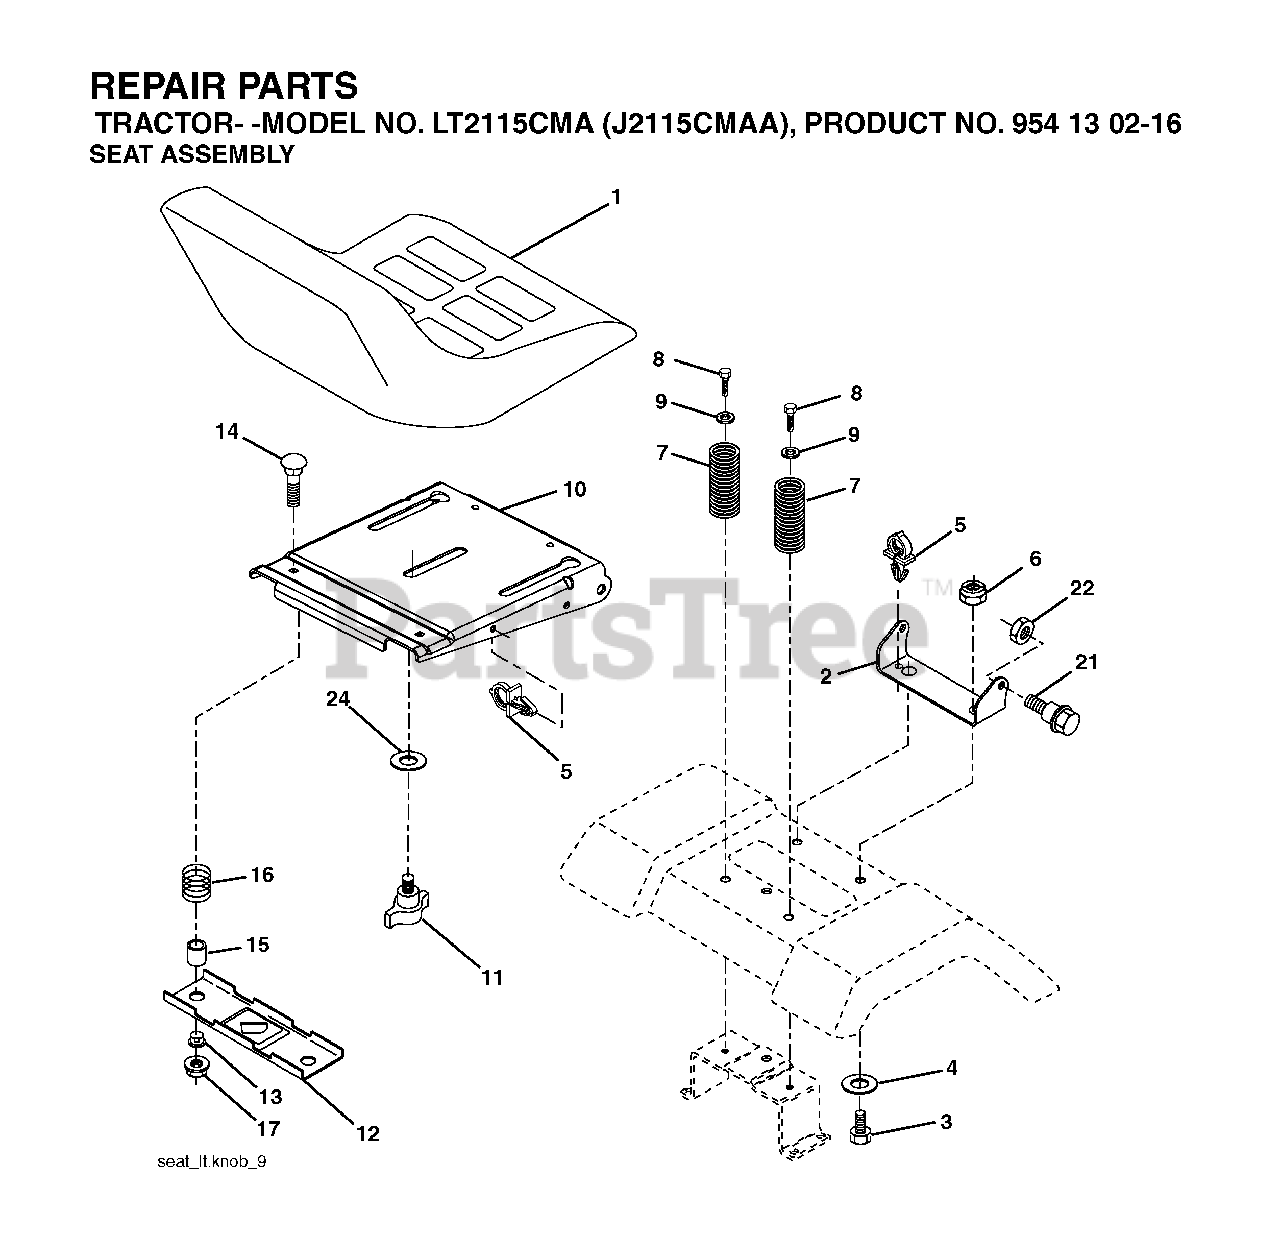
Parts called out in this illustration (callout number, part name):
2	BRKT.PIVOT.FENDER
4	WASHER PM
5	PUSH CLIP
6	NUT
7	SPRING COMPRESSION
8	SCREW 3/8-16X1
9	WASHER
11	KNOB.SEAT.ADJ.WINGNUT
12	BRKT SWITCH
14	BOLT.ROUND.HEAD.SQUARE.NECK
15	SPACER SPLIT 28X.96
17	NUT T
21	BOLT.SHOULDER.5/16-18
22	NUT.71038.31-18.HEX.NYLOCK
